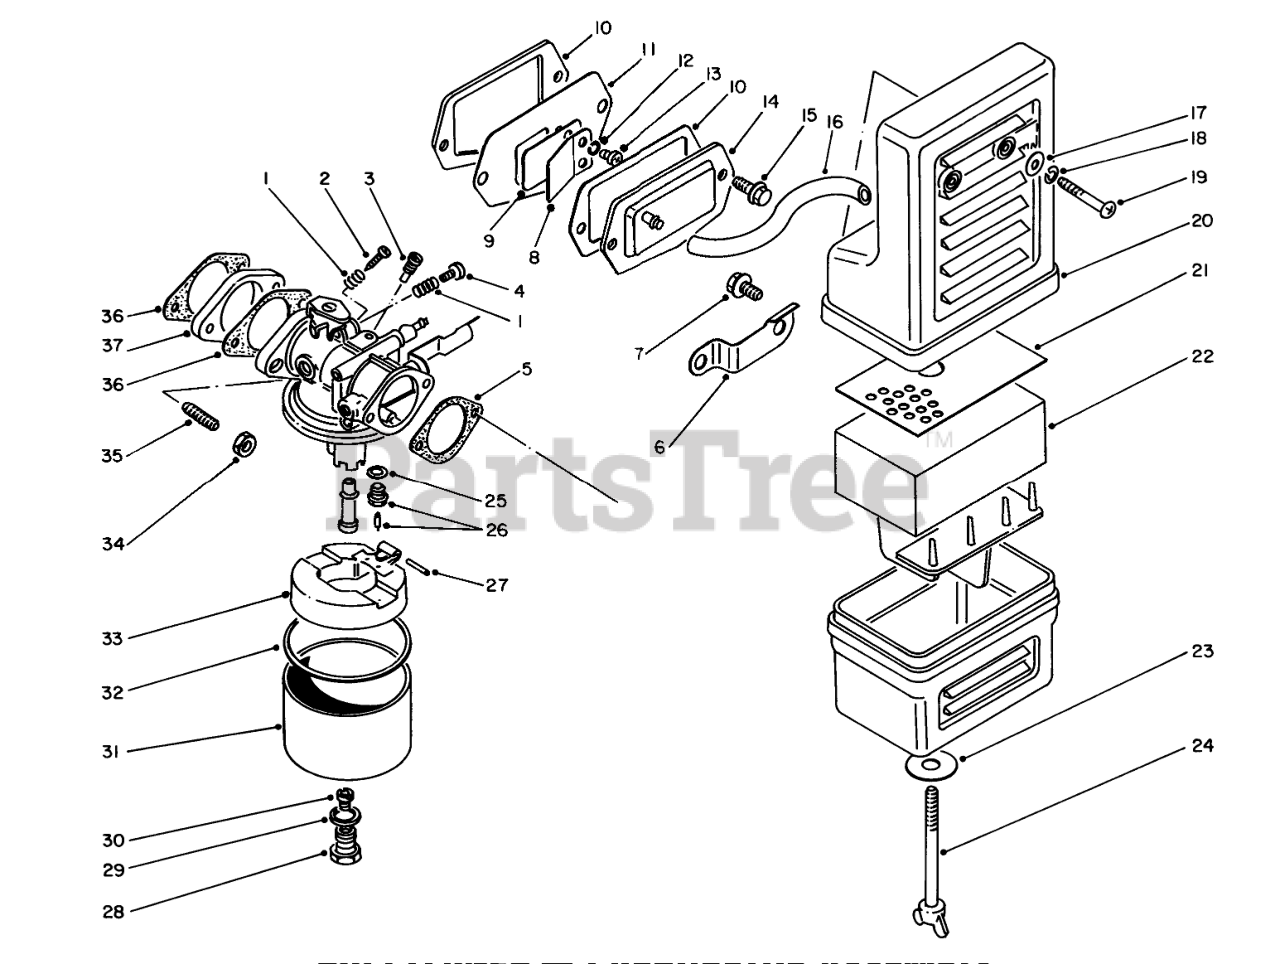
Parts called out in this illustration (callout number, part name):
1	Spring
2	ADJUSTER
3	PILOT JET
4	SCREW
5	AIR CLEANER GASKET
6	Bracket-Air Cleaner
8	Stopper
9	Reed Valve
10	Gasket
11	Reed Valve Assembly (Incl. Ref. #8 & 9)
12	Lockwasher
13	Screw
14	Cap-Breather
17	WASHER
18	Washer
19	SCREW
20	Air Cleaner Assembly (Incl. Ref. #21-24)
21	Holder
22	FILTER
23	WASHER
24	Bolt-Wing
25	GASKET
26	NEEDLE VALVE
29	Gasket
30	Jet-Main (75)
31	Carburetor Assembly (Incl. Ref. #25-30 & 32-33)
32	GASKET
33	FLOAT
35	Bolt-Stud
36	GASKET
37	INSULATOR
